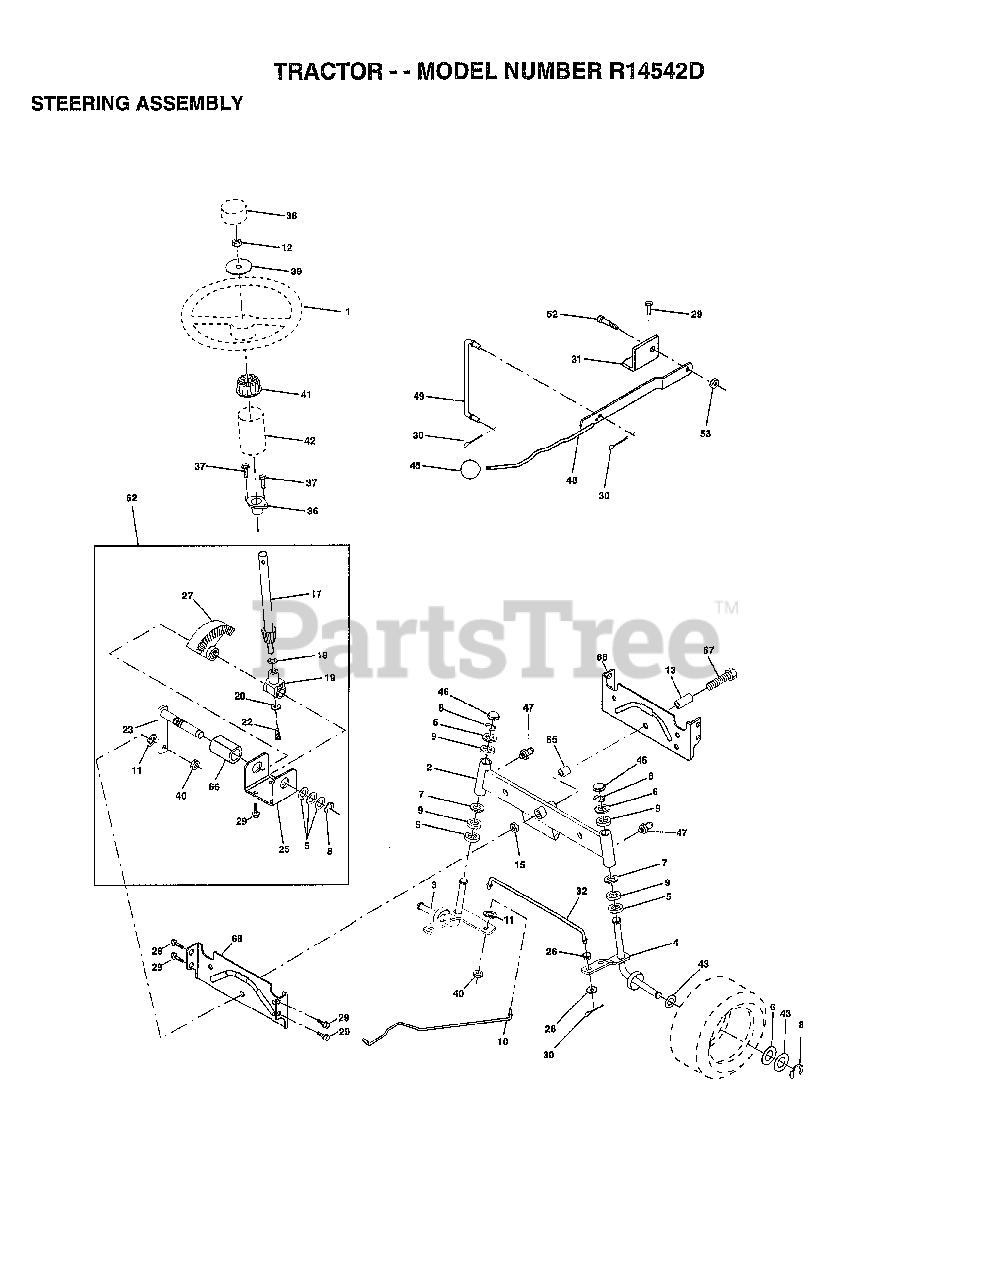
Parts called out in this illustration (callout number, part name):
2	AXLE ASM
3	SPINDLE.ASM.LH
4	"SPINDLE ASM,RH"
5	WASHER .T
6	WASHER
7	WASHER
8	RING
9	COL. SRTG. BEAR.
10	DRAGLINK-STAMPED
11	LOCKWASHER
13	BEARING AXLE
15	"NUT-LOC,FLANGE LT"
17	SHAFT ASM STEERNG
18	THRUST WASHER
19	SUPPORT.SHAFT
22	SCREW HEX SOC1/4-
25	BRKT-STEERING
26	BUSHING.DRAGLINK
27	GEAR SECTOR
28	WASHER
29	SCREW
30	COTTER PIN
31	BRKT.PVT.MAN.LVR.
32	TIE ROD
36	BUSHING.STRG.3/4
37	"SCREW-TT,10-32 FL"
38	ST WHL INSERT CAP
39	WASHER
40	GRIPCO NUT
41	ADAPTER LT
42	BOOT SHAFT STEER
45	KNOB.RD.7/16-14
46	CAP
47	ZERK M
48	LEVER.ASM.CLUTCH
49	LINK CLTCH W/NUTS
52	"BOLT, SHOULDER LT"
62	KIT STEERING ASM
65	SPACER AXLE
66	"BEARING-ARM,PITMA"
67	BOLT
68	BRACE AXLE
